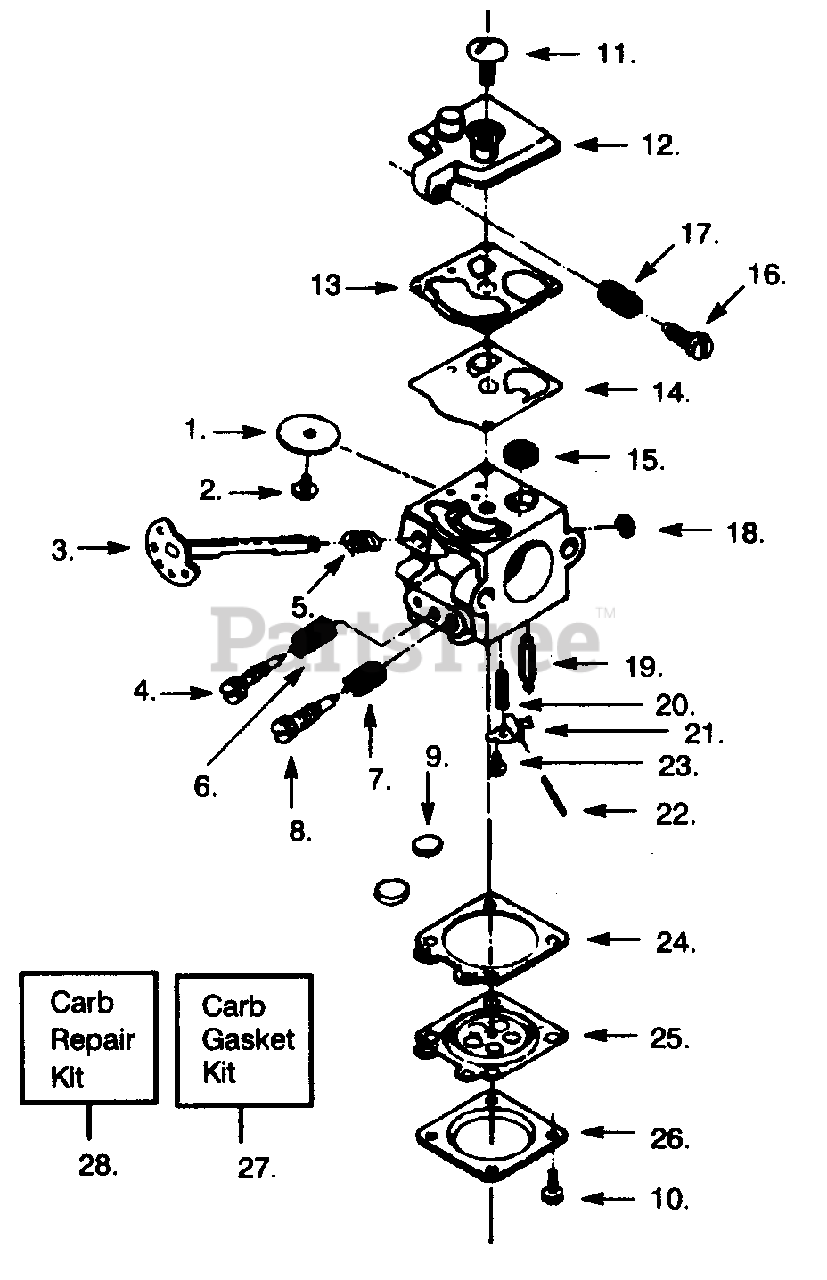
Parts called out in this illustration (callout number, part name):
1	Throttle Valve
2	Throttle Valve Screw
3	Throttle Shaft Ass'y.
4	Low Speed Mixture Needle
5	Throttle Return Spring
6	Low Speed Mixture Needle Spring
7	High Speed Mixture Spring
8	High Speed Mixture Needle
9	Plug-5/16 Dia. Welch
10	Metering Cover Screw Ass'y.
11	Pump Cover Screw
12	Fuel Pump Cover
13	Fuel Pump Gasket
14	Fuel Pump Diaphragm
15	Fuel Inlet Screen
16	Idle Speed Adjusting Screw
17	Idle Speed Adjusting Screw Spring
18	Throttle Retainer Ring
19	Inlet Needle Valve
20	Metering Lever Spring
21	Metering Lever
22	Metering Lever Pin
23	Metering Lever Pin Screw
24	Metering Diaphragm Gasket
25	Metering Diaphragm
26	Metering Diaphragm Cover
27	Carb. Gasket/Diaphragm (Incl. 13, 14, 24 & 25)
28	Carb. Repair Kit (Incl. 9, 13-15, & 19-25)
